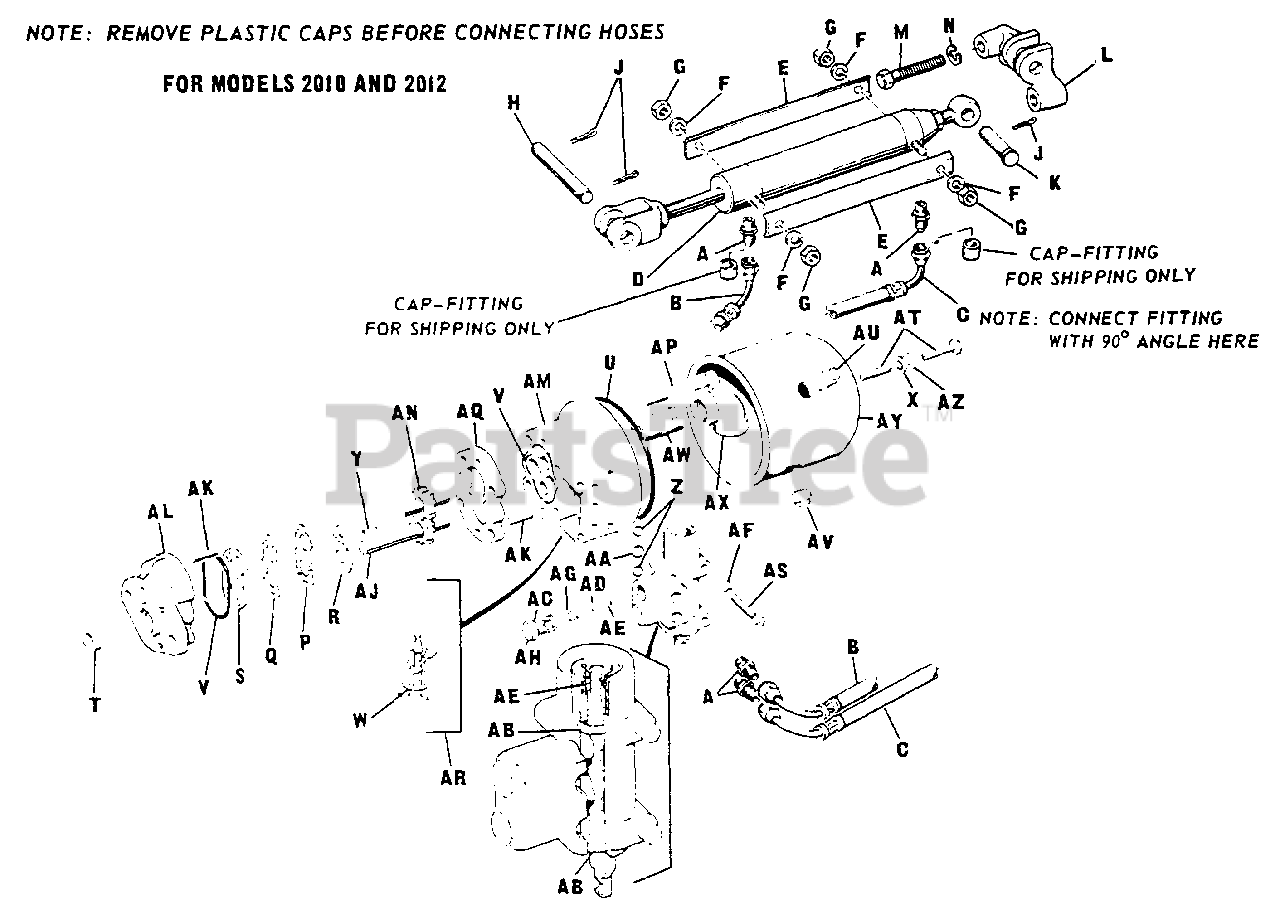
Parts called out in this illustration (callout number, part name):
B	Hose Assembly
C	Hose Assembly
D	Cylinder Assembly
F	Lock Washer 5/16"
G	Full Hex Nut 5/16"-18
J	Cotter Pin, 1/8" x 3/4"
K	Ram Bracket Pin
L	Ram Bracket
M	Hex Cap Screw 7/16"-14 x 2-1/4"
N	Lock Washer, 7/16"
P	Heat Shield (for service only)
Q	Gasket (for service only)
R	Wear Plate (for service only)
S	Seal (for service only)
T	Rotary Seals (for service only)
U	"O" Ring (for service only)
V	"O" Ring (for service only)
W	"O" Ring (for service only)
X	Stat-O-Seal (for service only)
Y	Shaft Drive Key (for service only)
Z	"O" Ring (for service only)
AA	"O" Ring (for service only)
AB	"O" Ring (for service only)
AC	"O" Ring (for service only)
AD	Ball (for service only)
AE	Pin Cam (for service only)
AF	Lock Washer 1/4"
AG	Spring (for service only)
AH	Cage (for service only)
AJ	Drive Gear Assy. (for service only)
AK	Dowel Pin (for service only)
AL	Front Cover Assy. (for service only)
AM	Back Cover Assy. (for service only)
AN	Drive Gear Assy. (for service only)
AP	Bolt (for service only)
AQ	Center Sect Mach. (for service only)
AR	Relief Valve Assy. (for service only)
AS	Screw (for service only)
AT	Screw (for service only)
AU	Filler Cap Plug (for service only)
AV	Drain plug (for service only)
AW	Inlet Nipple (for service only)
AX	Inlet Elbow (for service only)
AY	Tank Assembly (for service only)
AZ	Flat Washer, 1/4" (for service only)
